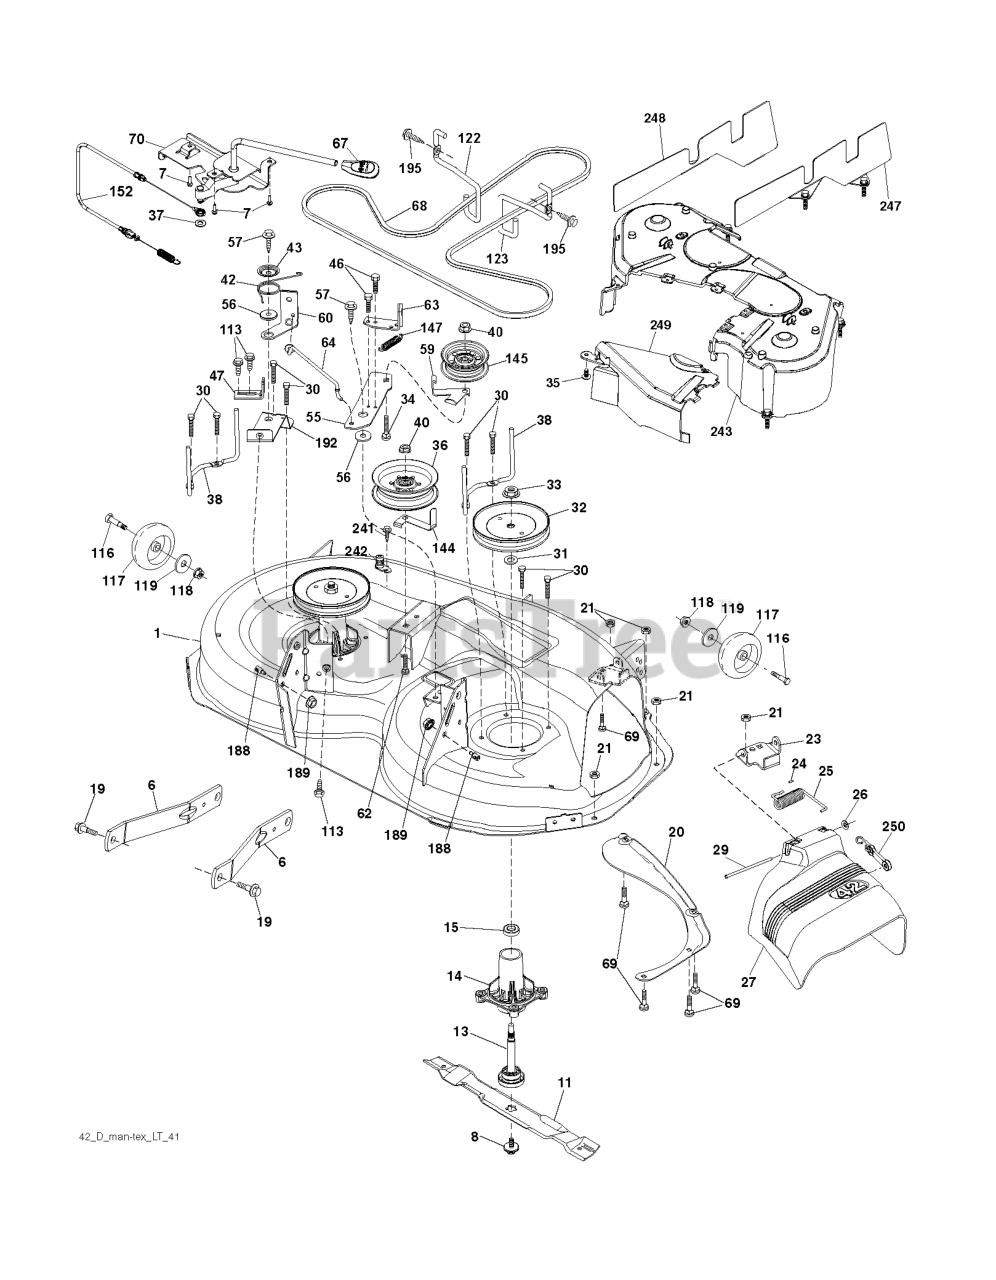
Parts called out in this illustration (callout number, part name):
1	DECK.WELDMENT.42"
6	ARM.SUSPENSION.MOWER.R
7	SCREW.#10 X 0.750.BOS
8	BOLT.WASHER.ASM.7/16-2
11	42" HI-LIFT BLADE
13	SHAFT.ASM.MDRL.N/GREASE.38
14	RP.HOUSING.MANDREL.4PT.
19	BOLT.SHOULDER
20	BAFFLE.VORTEX
21	LOCKNUT
23	BRKT.DEFLECTOR.38"2005+
24	CAP-SLEEVE LT
25	SPRING.TORSION.DEFLECT
26	NUT PUSH M
27	DEFLECTOR ASM.42"TEX.FRENCH
29	ROD.HINGE
30	SCREW, WASHER HEAD
31	WASHER.SPACER.MANDREL
32	PULLEY.MANDREL.5.438.PD
33	NUT.FLANGE.LOCK.TOP
34	BOLT.3/8-16X1.50
35	FASTENER.XMAS.TREE
36	PULLEY.IDLER.2006
37	WASHER
38	KEEPER.BELT.LH.MANDREL
40	NUT LOCK FLG 3/8-16 UNC
42	SPRING.TORSION.BRAKE
43	SRPING.TORSION.RETAINE
46	SCREW.1/4-20X5/8
47	BRKT.CLUTCH.CABLE
55	IDLER.ARM.42"
56	SPACER.RETAINER
57	SCREW 3/8-16X1
59	GUARD, BELT
60	ARM BRAKE MOWER
63	ARM BRAKE MOWER
64	LINK BRAKE
67	HANDLE.CLUTCH.CABLE.LT
68	BELT.DECK.DRIVE.42"
69	BOLT
70	CLUTCH.ASM.MANUAL.LT.PRED
113	BOLT.5/16HEX.WHS.HD
116	BOLT M
117	WHEEL.GAGE.HALF.SPOKED
118	LOCKNUT
119	WASHER.5/16.FLAT.STE.STD.
122	KEEPER BELT ENGINE LH
123	KEEPER BELT RH
144	KEEPER.BELT.MOWER
145	PULLEY.IDLER.48"PRIMARY
147	RETURN SPRING
152	CLUTCH CABLE
188	STUD.FASTNER.W/ANTI-ROTATE
189	NUT LOCK HEX FLANGE 5/16-18
192	BRKT.BRAKE.STAND.LH.
195	SCREW, 3/8-16X3/4
241	SCREW.TT.#10-32X.5.3/8.FLANGE
242	PORT.WASHOUT
243	COVER DECK
247	SHIELD RIGHT
248	SHIELD LEFT
249	COVER CABLE CLUTCH
250	ELASTIC STRAP KIT
